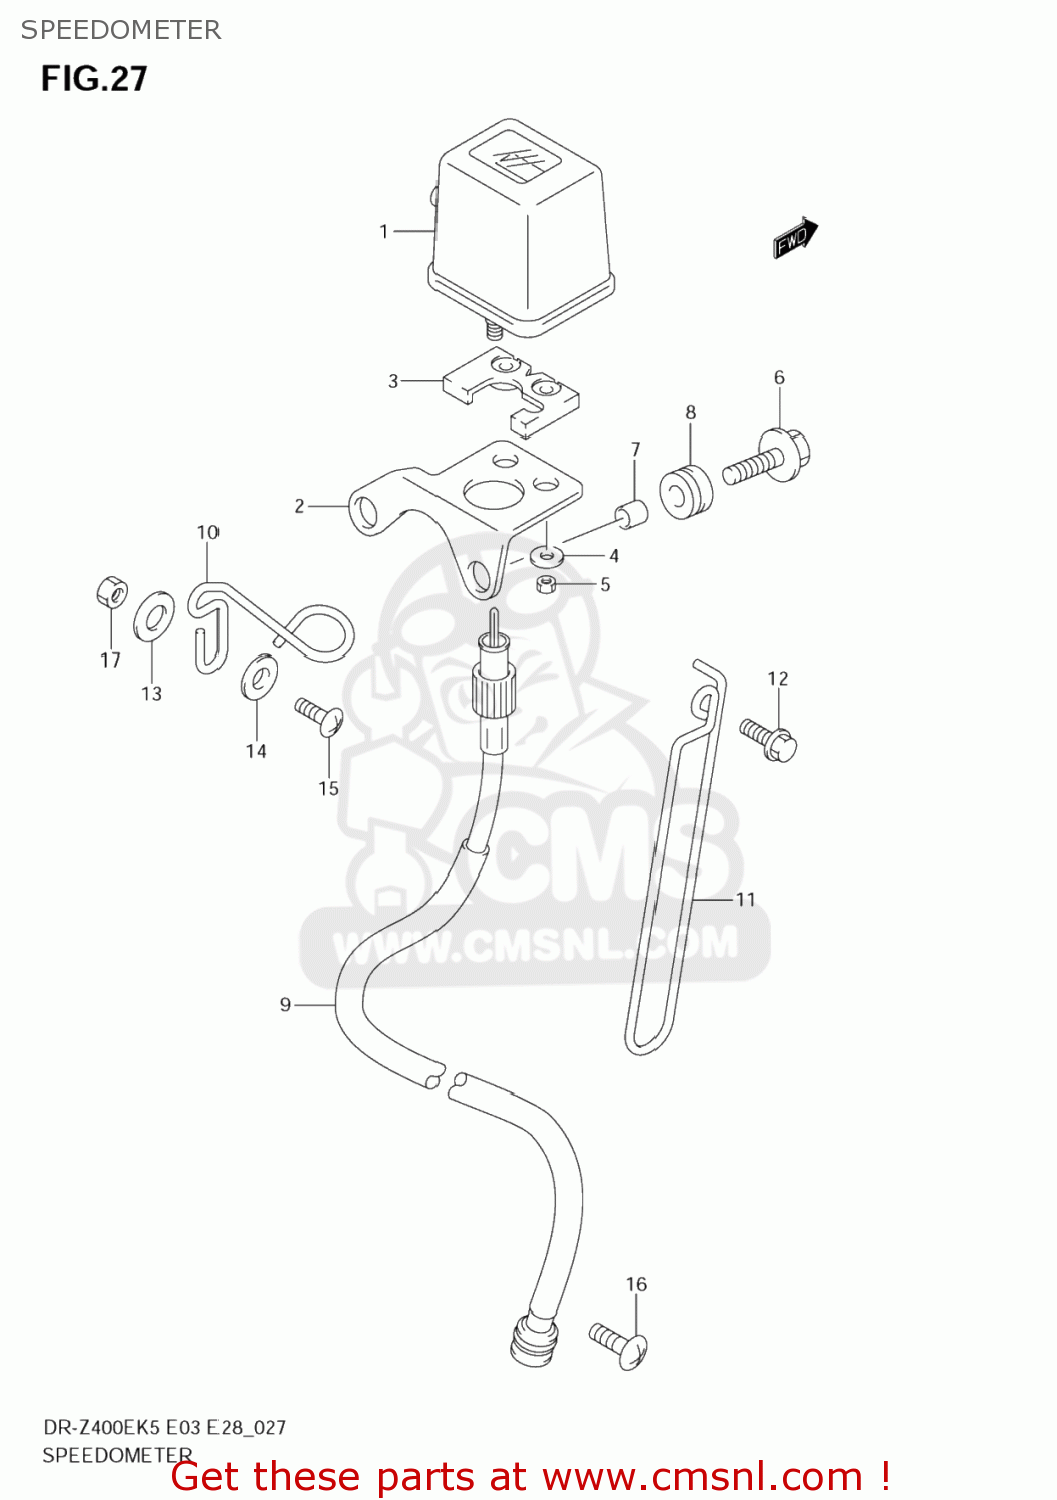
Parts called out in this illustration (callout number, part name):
1	TRIP METER
2	BRACKET
3	CUSHION
4	WASHER (4.3X13X0.80)
5	NUT
6	BOLT(6X25)
7	SPACER(6.1X8X9.5)
8	CUSHION
9	CABLE ASSY,SPEEDOMETER
10	GUIDE,SPEEDOMETER CABLE
11	GUIDE,METER CABLE NO.2
12	BOLT(6X20)
13	WASHER(6.5X18X1.6)
14	WASHER
15	SCREW
16	SCREW
17	NUT 6MM
